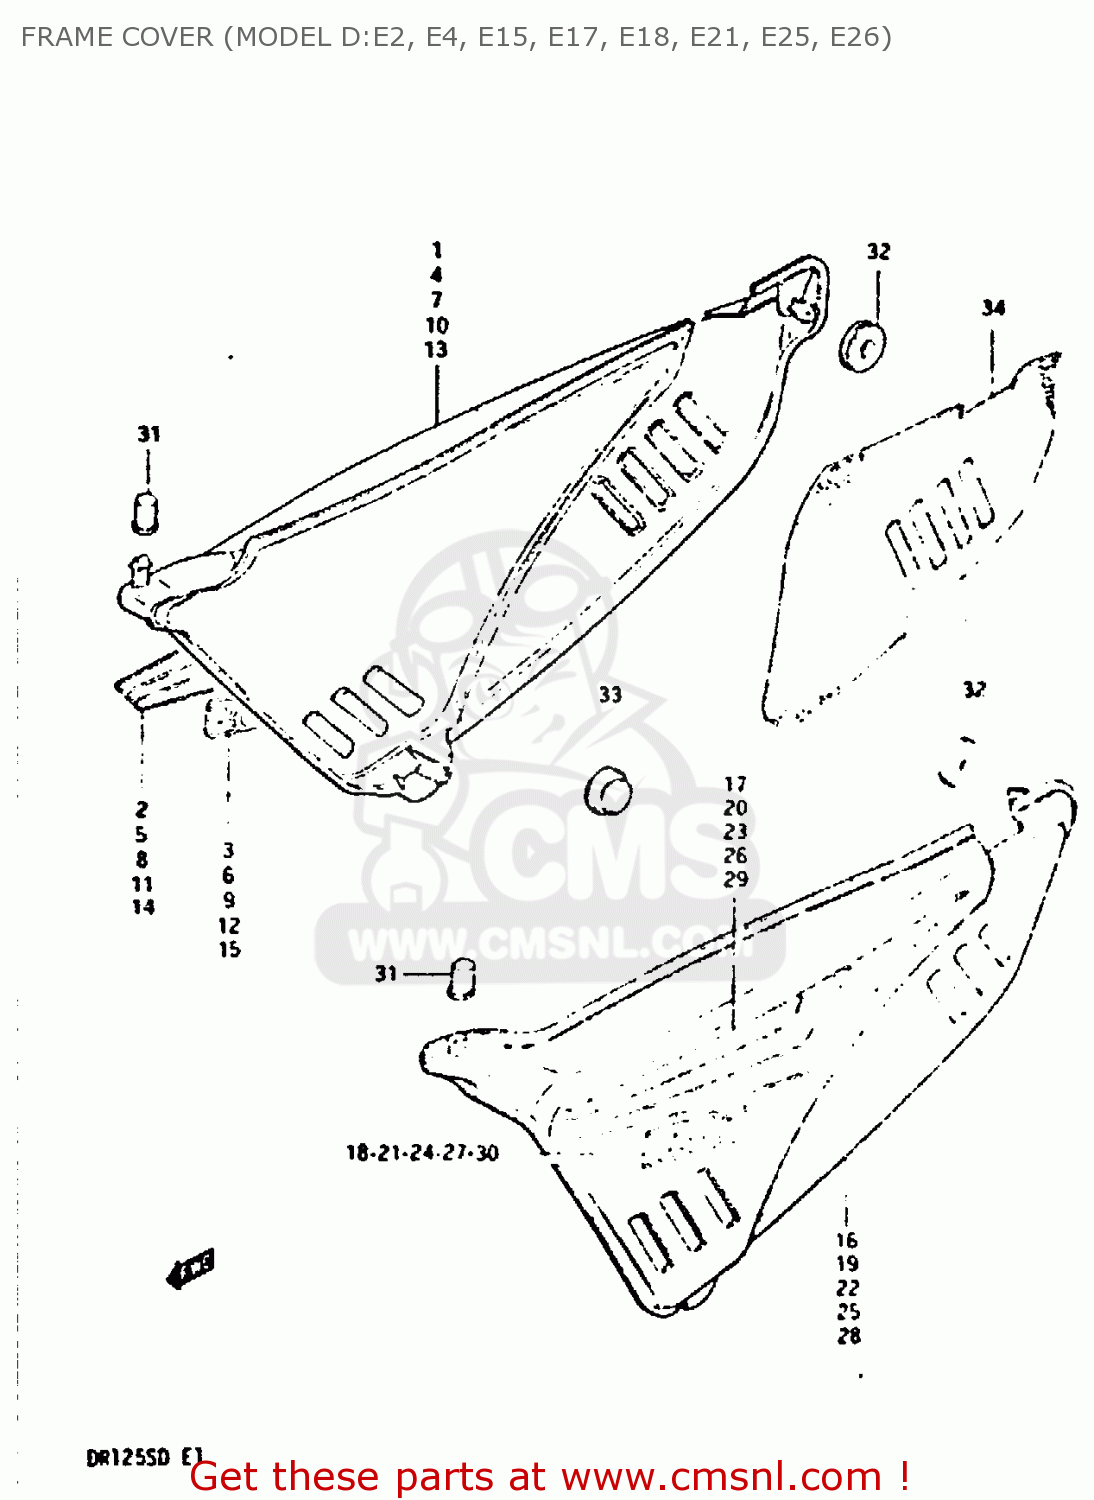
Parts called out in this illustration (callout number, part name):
1	COVER, FRAME RH (BLACK)
2	TAPE SET, FRAME COVER RH
3	EMBLEM, LH
4	COVER, FRAME RH (BLUE)
5	TAPE SET, FRAME COVER RH
6	EMBLEM, LH
7	COVER,FRAME,RIGHT
8	TAPE SET, FRAME COVER RH
9	EMBLEM, LH
10	COVER, FRAME RH (WHITE)
11	TAPE SET,FRAME COVER,RIGHT
12	EMBLEM
13	COVER, FRAME RH (YELLOW)
14	TAPE SET, FRAME COVER RH
15	EMBLEM
16	COVER, FRAME LH (BLACK)
17	TAPE SET, FRAME COVER LH
18	EMBLEM, LH
19	COVER, FRAME LH (BLUE)
20	TAPE SET, FRAME COVER LH
21	EMBLEM, LH
22	COVER, FRAME LH (RED)
23	TAPE SET, FRAME COVER LH
24	EMBLEM, LH
25	COVER, FRAME, LH
26	TAPE SET,FRAME COVER
27	EMBLEM
28	COVER, FRAME LH (YELLOW)
29	TAPE SET, FRAME COVER LH
30	EMBLEM
31	CUSHION
32	CUSHION
33	CUSHION
34	HEAT SHIELD,FRAME COVER
